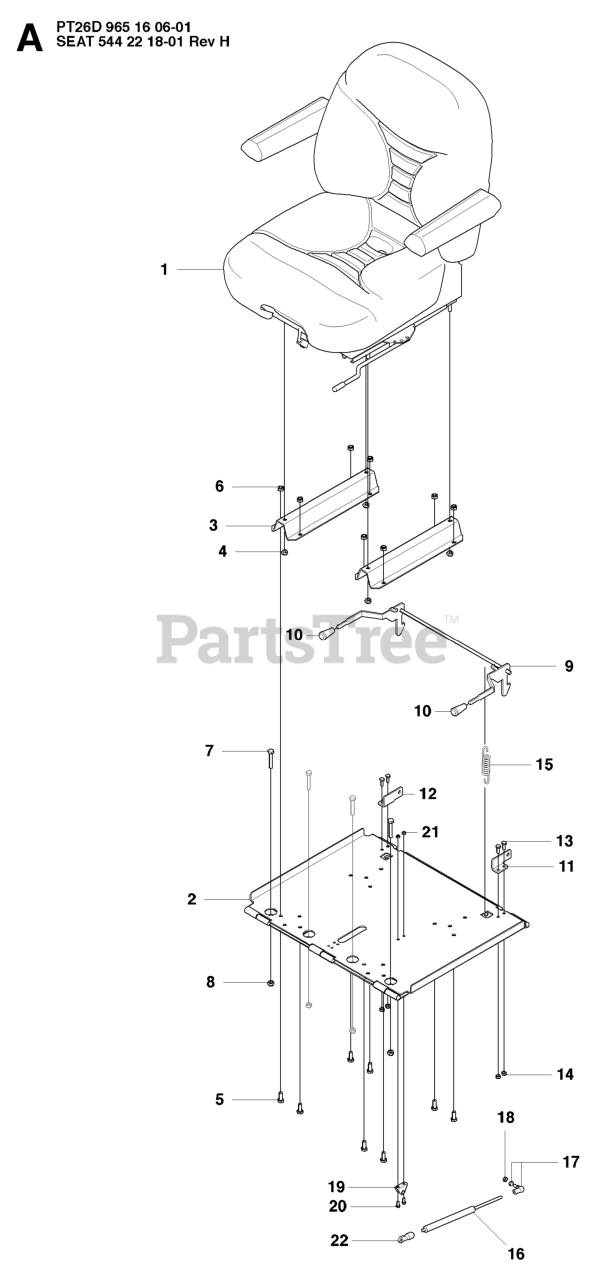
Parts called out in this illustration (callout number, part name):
4	LOCKNUT M8
5	SCREW 8X20
6	LOCKNUT M8
7	SCREW
8	LOCKNUT M8
13	BOLT FLANGE - M6X20
14	LOCKNUT M6
15	DRAW SPRING L=50
18	LOCKNUT M6
20	SCREW
21	LOCKNUT M5
